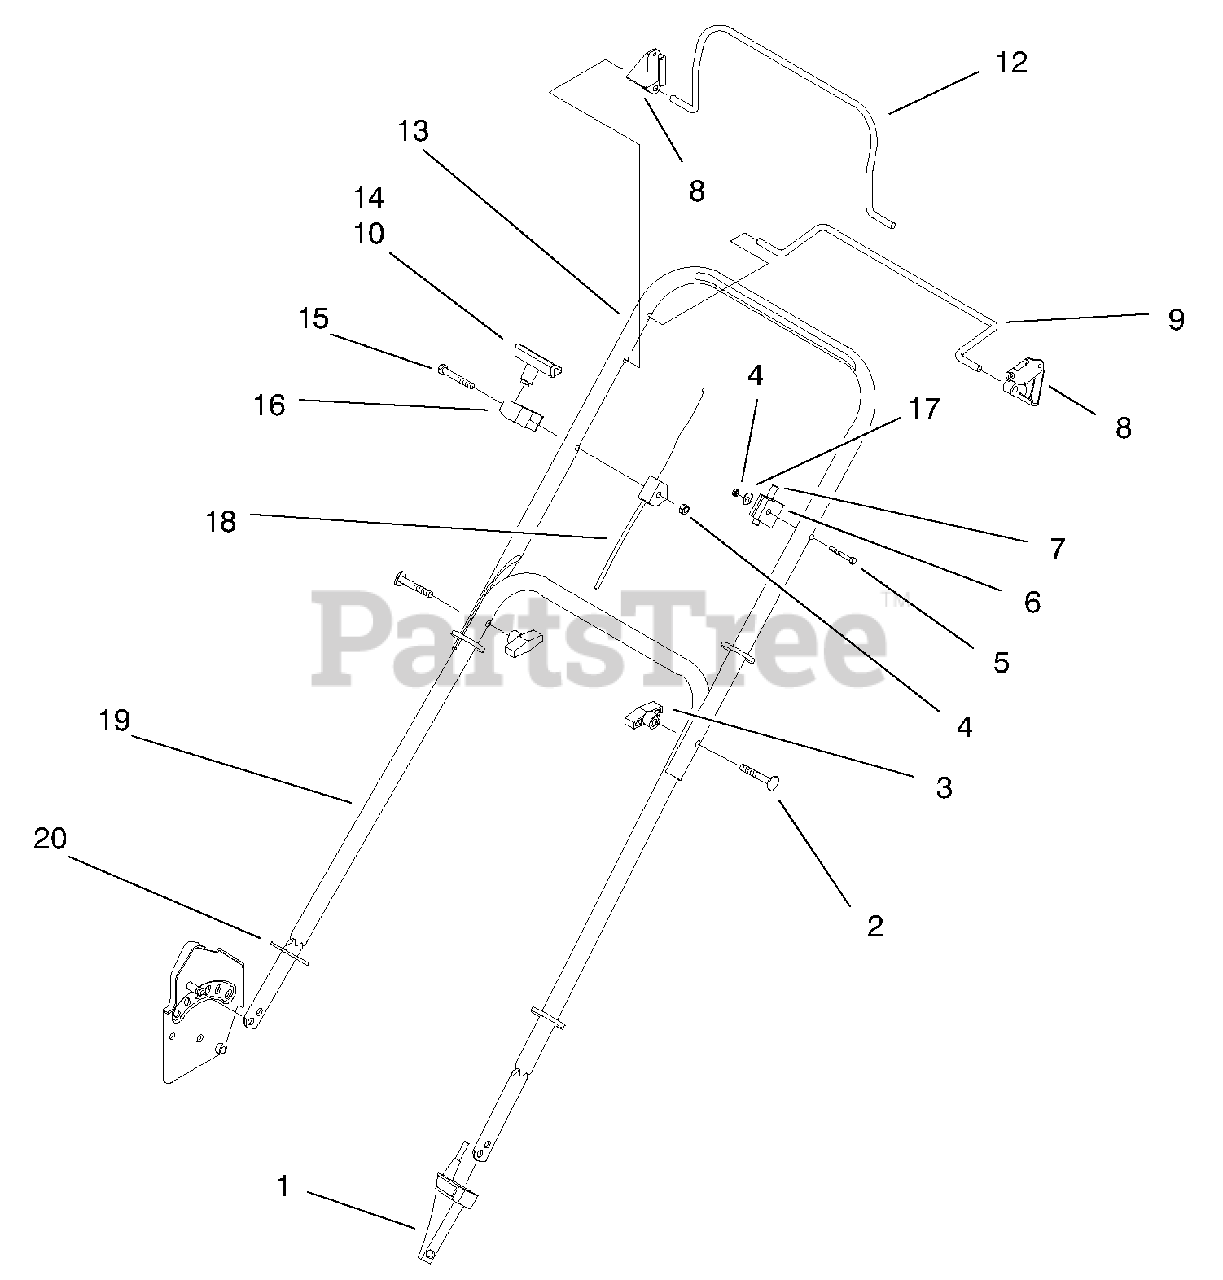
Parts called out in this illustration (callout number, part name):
1	Anchor-Cable
2	Screw-HH
3	Knob-Handle
4	Nut-Lock
5	Screw-Handle
6	Anchor-Upper Sp Cable
7	Cable-Traction
8	Stop-Pivot
9	Bail-Sp Control
10	Handle Staple
12	Bail-Brake
13	Handle-Upper
14	Handle-Starter
15	Screw-HH
16	Rope-Guide
17	Washer-Flat
18	ASM Brake Cable
19	Section-Lower Handle
20	Guard-Handle
